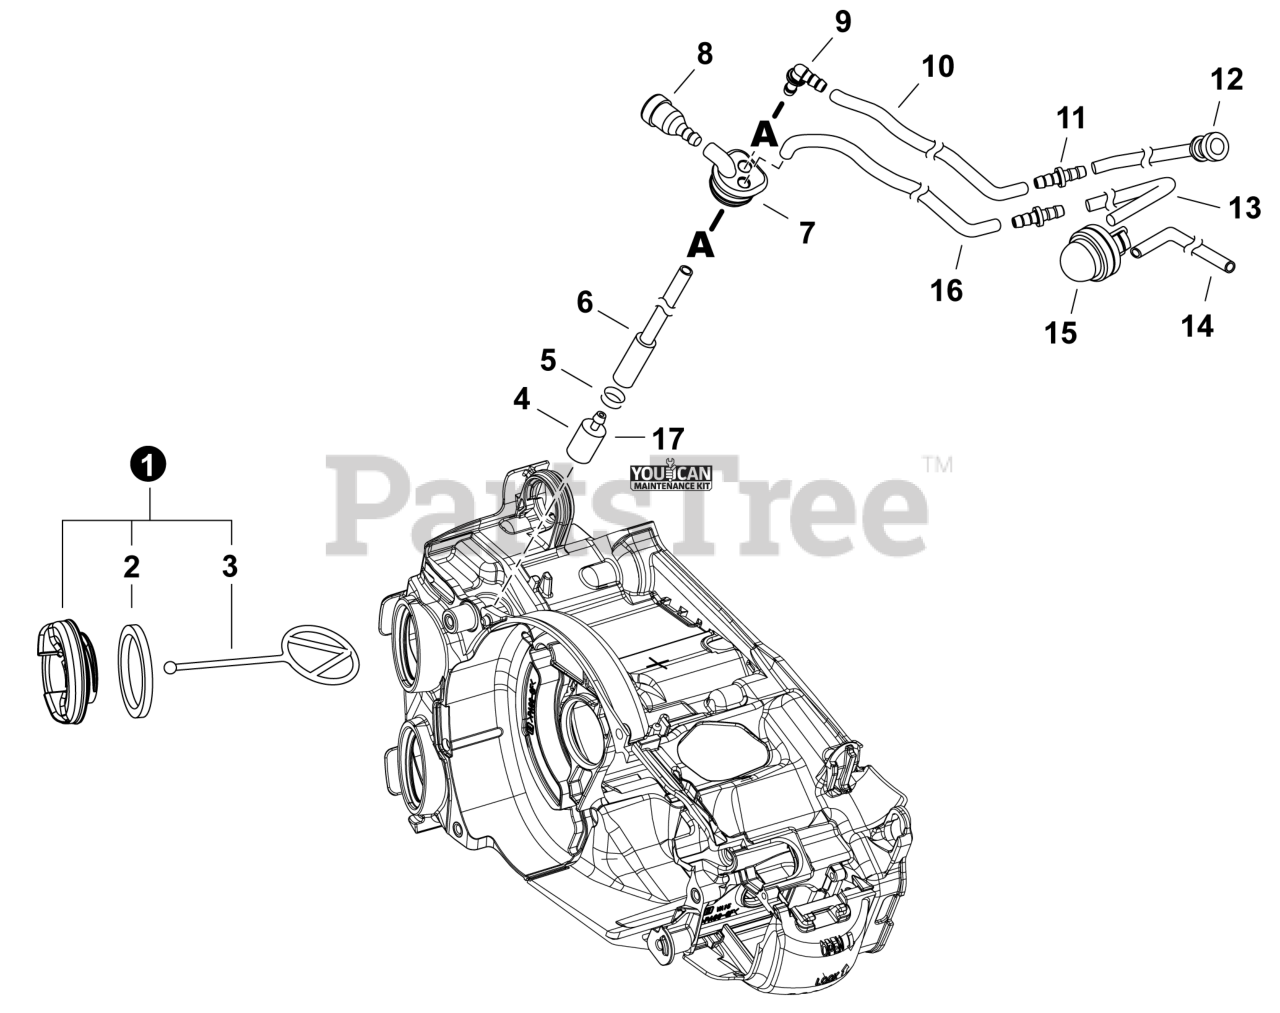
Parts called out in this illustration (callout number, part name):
1	CAP ASSY, FUEL
2	GASKET, CAP
3	CONNECTOR, CAP L= 60 MM
4	FILTER, FUEL
6	PIPE, FUEL
7	GROMMET, FUEL
8	VENT ASSY
9	CONNECTOR, PIPE
10	PIPE, FUEL 3x5x95 BLACK
11	CONNECTOR, PIPE
12	PIPE, FUEL
13	PIPE, FUEL 3x5x56.5 BLACK
14	PIPE, FUEL 2.5x4.5 BLACK
15	BULB, PURGE
16	PIPE, FUEL 3x5x115 BLACK
17	TUNE-UP KIT - YOUCANT
